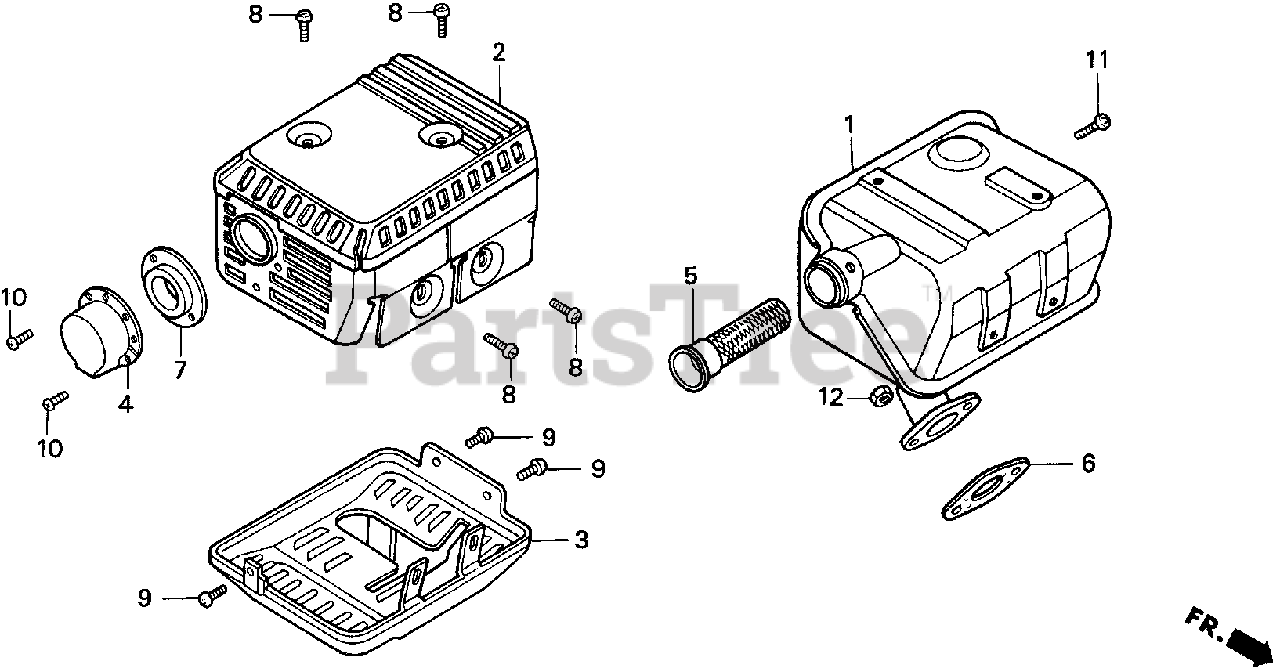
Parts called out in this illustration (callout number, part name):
1	MUFFLER
2	PROTECTOR, MUFFLER
5	ARRESTER, SPARK
6	GASKET, MUFFLER
8	SCREW, TAPPING (5X8)
11	SCREW, TAPPING (4X6)
12	NUT, HEX. (8MM)
